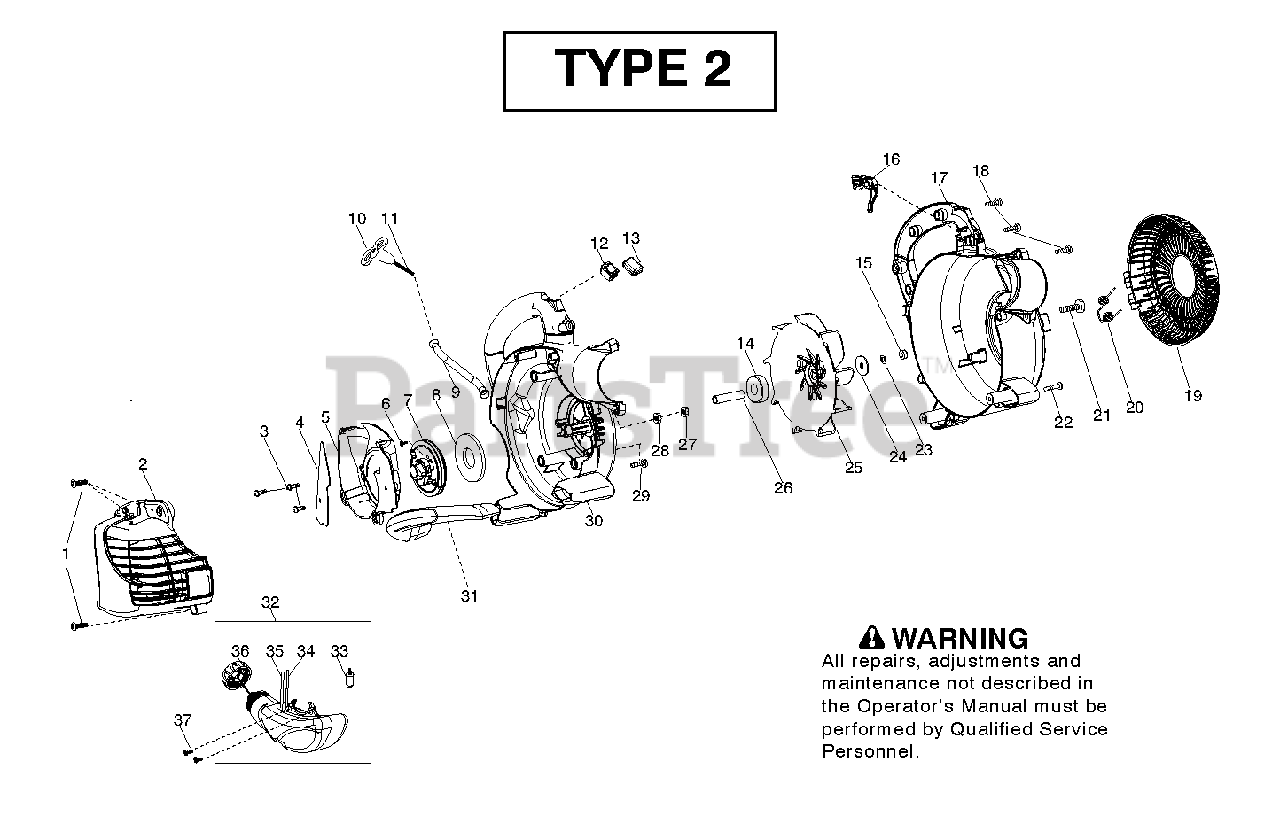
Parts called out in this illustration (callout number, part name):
2	ASSY COVER ENGINE
4	SHIELD BAFFLE
6	SCREW SEMS TOOTHED WASHER
7	KIT STARTER PULLEY
8	KIT STARTER SPRING
9	TUBE STARTER ROPE
10	HANDLE STARTER BLK
12	KIT SWITCH
13	PROTECTOR, SWITCH
16	TRIGGER THROTTLE RED
17	COVER
19	DOOR VAC BLACK
20	SPRING VAC DOOR
22	SCREW #10 PLASTITE 1.362
24	WASHER, IMPELLER
25	ASSY IMPELLAR HUB
26	SPACER FLYWHEEL
30	ASSY SCROLL RIGHT
31	HANDLE VAC BLACK
32	Fuel Tank Assembly, Non Low Perm St
33	FUEL PICK-UP ASSY
36	ASSY FUEL CAP W/RETAINER
37	SCREW FUEL TANK RETAINER
